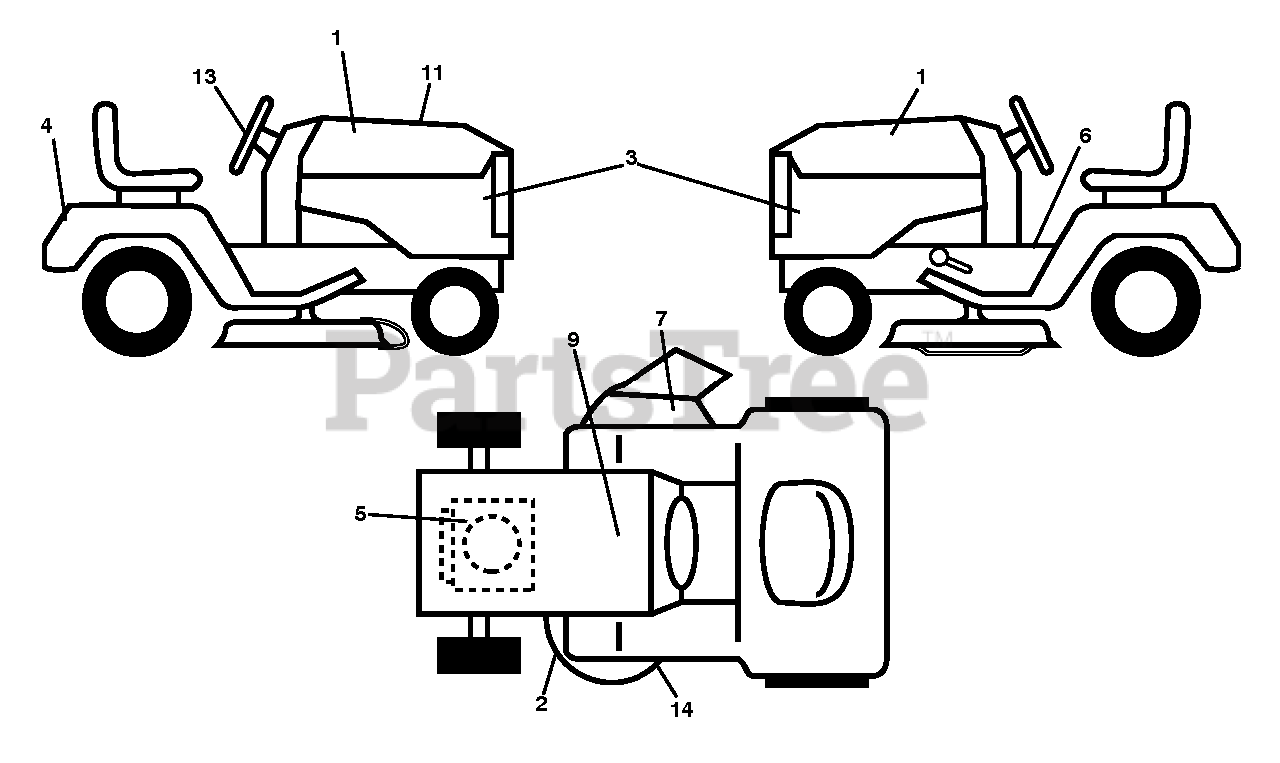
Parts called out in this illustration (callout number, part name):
1	DECAL.POULAN PRO.2015
3	DECAL TRACTOR SIDE PANEL DECAL
4	DECAL.REARFNDR.POULAN PRO.2015
5	Decal, Engine BS 22INTK DOM 381708
6	DECAL.WARNING.2007.ENG/FR
7	DECAL, DECK DEFLECTOR, WARNING
9	DECAL BTRY SYMBOLS
11	DECAL DECAL.RPL.BSM44.INTK.TLW
13	DECAL.STRWHL.BLK.2014.PPRO
14	DECAL.MOWER.SCH.48/54.PREM
